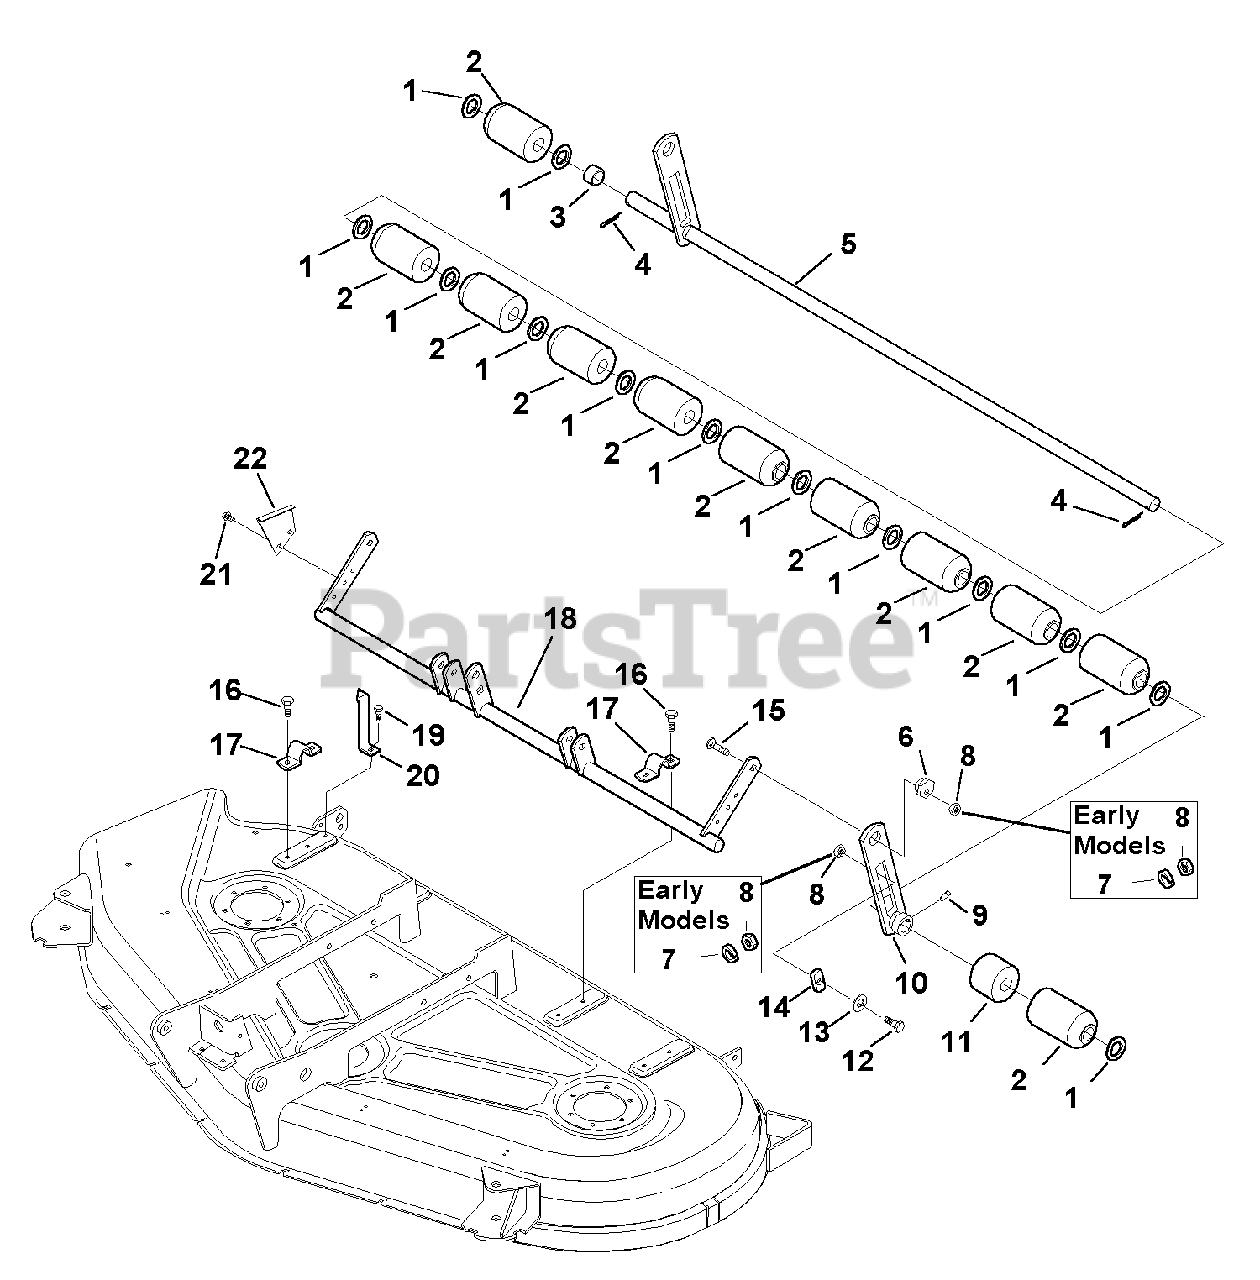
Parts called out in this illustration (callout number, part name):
3	SPACER, Short
4	PIN, Cotter, 3/16 x 1-1/2
5	ASSEMBLY, Roller Shaft & Bar
6	NUT, Hex Adjusting, .99 DIA .687
7	LOCKWASHER, 3/8 (Early Models)
8	NUT, Hex Alm Insert Lock, 3/8-16 (Later Models)
8	NUT, 3/8-16 (Early Models)
9	SET SCREW, Square Head, 5/16-18 x 1/2, G8
10	ASSEMBLY, Roller Bar
11	ROLLER, Short
12	BOLT, Shoulder, 3/8-16 X 1.34
13	WASHER, 1/2 x 1-1/4
15	CARRIAGE BOLT, 3/8-16 x 1-1/2
16	CAPSCREW, Hex Head, Taptite, 5/16-18 x 3/4
17	STRAP
18	ASSEMBLY, Rocker Shaft & Lever
19	CAPSCREW, Hex Head, Taptite, 5/16-18 x 7/8
20	INDICATOR, Height of Cut
21	CAPSCREW, Hex Head, Taptite, 5/16-18 x 1/2
22	BRACKET, Height of Cut
